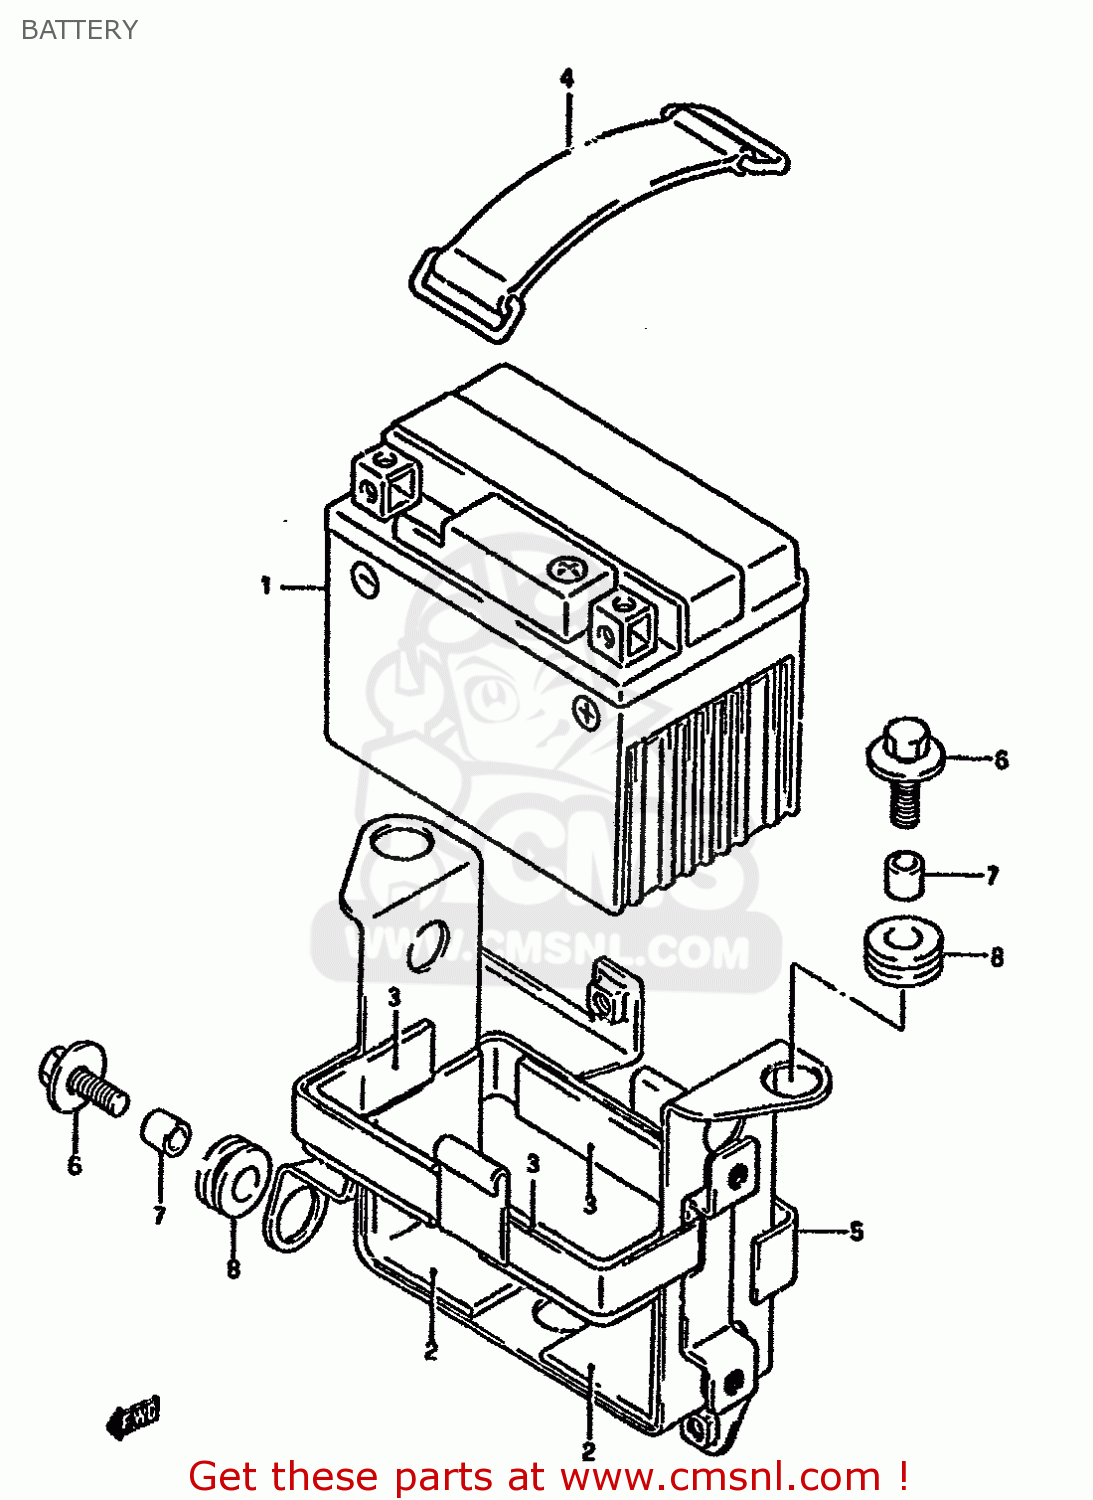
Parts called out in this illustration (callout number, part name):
1	BATTERY,YT4L-B
2	PROTECTOR(170X95X3.0)
3	PROTECTOR,20X9
4	BAND
5	HOLDER COMP,BATTERY
6	BOLT
7	SPACER(6.1X9X7.5)
8	CUSHION
